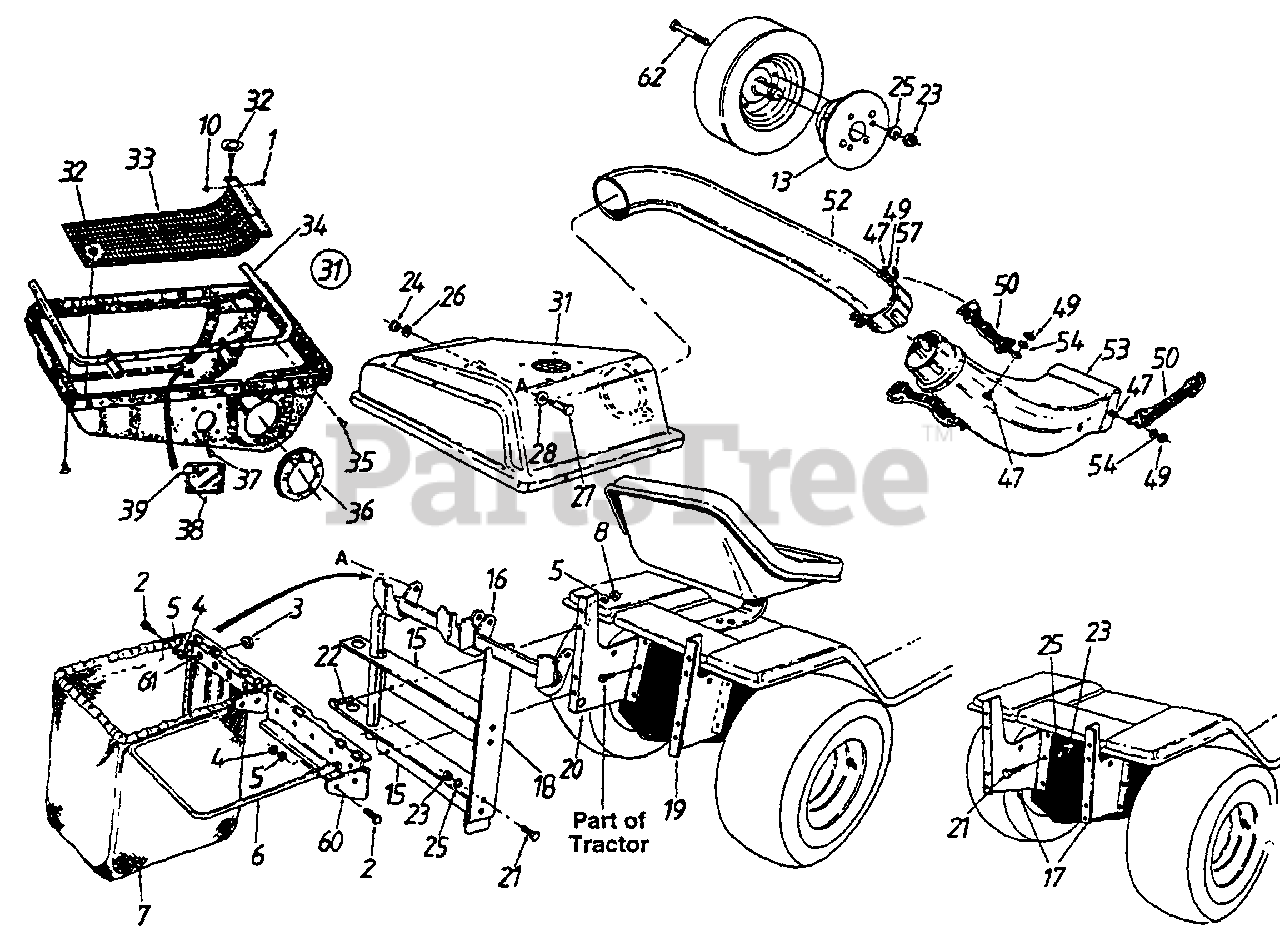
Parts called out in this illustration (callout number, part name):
1	Pop Rivet .188 Dia.
2	Hex Bolt 1/4-28 x .88" Lg.
3	Hex Sems Nut #10-24 Thd.
4	Hex Nut 1/4-28 Thd.
5	L-Wash. 1/4" I.D.
7	Grass Catcher Bag
8	Hex Nut 1/4-20 Thd.
10	Flat Wash. 1/4" I.D.
22	Hex Bolt 1/4-20 x .62" - Gr. 5
23	Hex Nut 5/16-18 Thd.
24	Hex Nut 3/8-16 Thd.
25	L-Wash. 5/16" I.D.
26	L-Wash. 3/8" I.D.
27	Shld. Bolt 3/8-16 x .50" Dia.
28	Bell-Wash .505" l.D. x 1.0" O.D.
31	Grass Catcher Cover Ass'y.
32	Twist Fastener
35	Hex AB-Tap Scr. 1/4 x .62"
37	Truss B-Tap Scr. #10 x .5"
38	Plastic Plate
39	Speed Nut
47	Hex Bolt 1/4-20 x .625"
49	Hex Ins. L-Nut 1/4-20 Thd.
50	Retainer Strap Ass'y.
52	Catcher Tube
53	Discharge Chute
54	L-Wash .27" l.D.
57	Retainer Hook Brkt.
61	Truss Mach. Scr. #10-24 x .5"
62	Hex Bolt 5/16-18 x .4" Lg.
